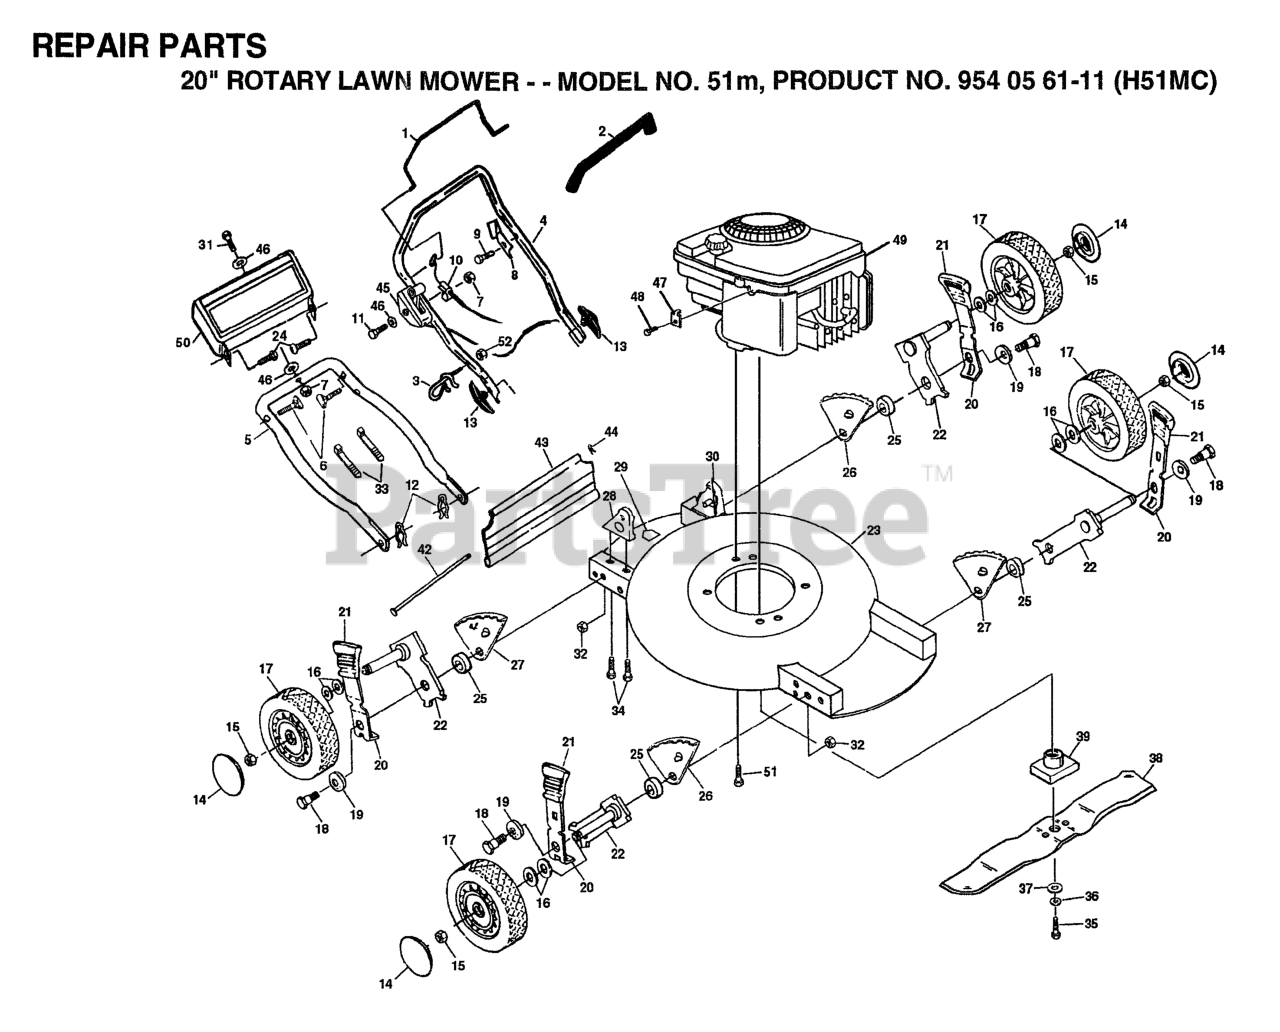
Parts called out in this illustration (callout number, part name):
1	CONTROL BAR/GREY
2	HANDLE GRIP
3	ROPE GUIDE
4	UPPER HANDLE
5	HANDLE, LOWER PM
6	HANDLE BOLT
7	NUT
8	BRACKET UPSTOP
9	TAPPING SCREW
10	CABLE ASSEMBLY
11	SCREW**
12	HAIRPIN COTTER
13	KNOB HANDLE
15	HEX FLANGE LOCKNT
16	WAVE WASHER
17	WHL & TIRE ASSEMBLY
18	SHOULDER BOLT PM
19	WASHER.BELLEVILLE (3 2 LB)
20	SELECTOR SPRING
21	SELECTOR KNOB
22	AXLE ARM ASSY FT
25	SPACER PM
26	WHL ADJ BRKT RF/LR
27	WHL ADJ BRKT LF/RR
28	HANDLE BRACKET ASS'Y (RIGHT)
29	DECAL HYT
30	HANDLE BRACKET ASS'Y (LEFT)
31	SCREW
32	LOCKNUT PM
33	TIE GUIDE
34	SCREW
35	SCREW, HEX HD 3/8-24 X 1-3/8
36	LOCKWASHER
37	WASHER,HARDEN
38	BLADE 20"
39	BLADE ADAPTOR
42	ROD.SKIRT.14.06.MULCHER.20
43	DEFLECT. REAR PM
44	RETAINER CLIP
45	THROTTLE CONTROL
48	SCREW.HEX.HEAD.WASHER.10-16
50	TRIM PLATE
51	BOLT
52	NUT
